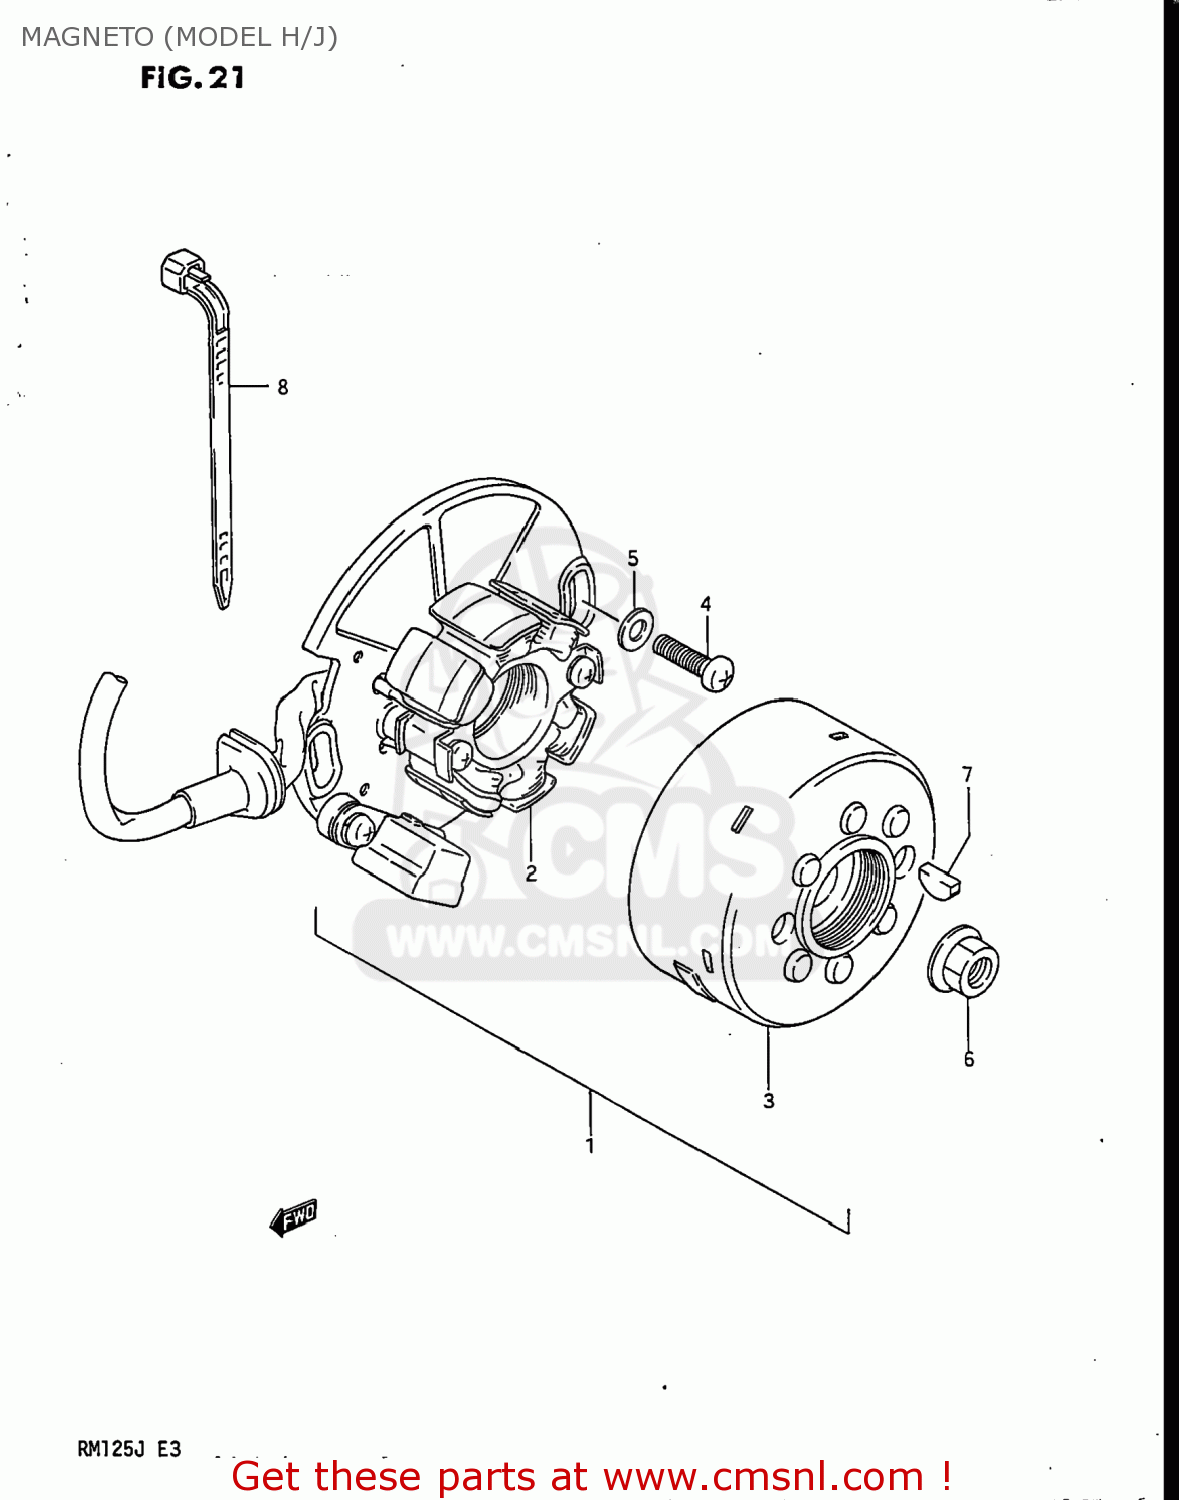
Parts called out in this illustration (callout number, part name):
1	MAGNETO ASSEMBLY
2	STATOR ASSEMBLY
3	ROTOR
4	SCREW
5	WASHER
6	NUT
7	KEY 4MM
8	CLAMP(L:125)
